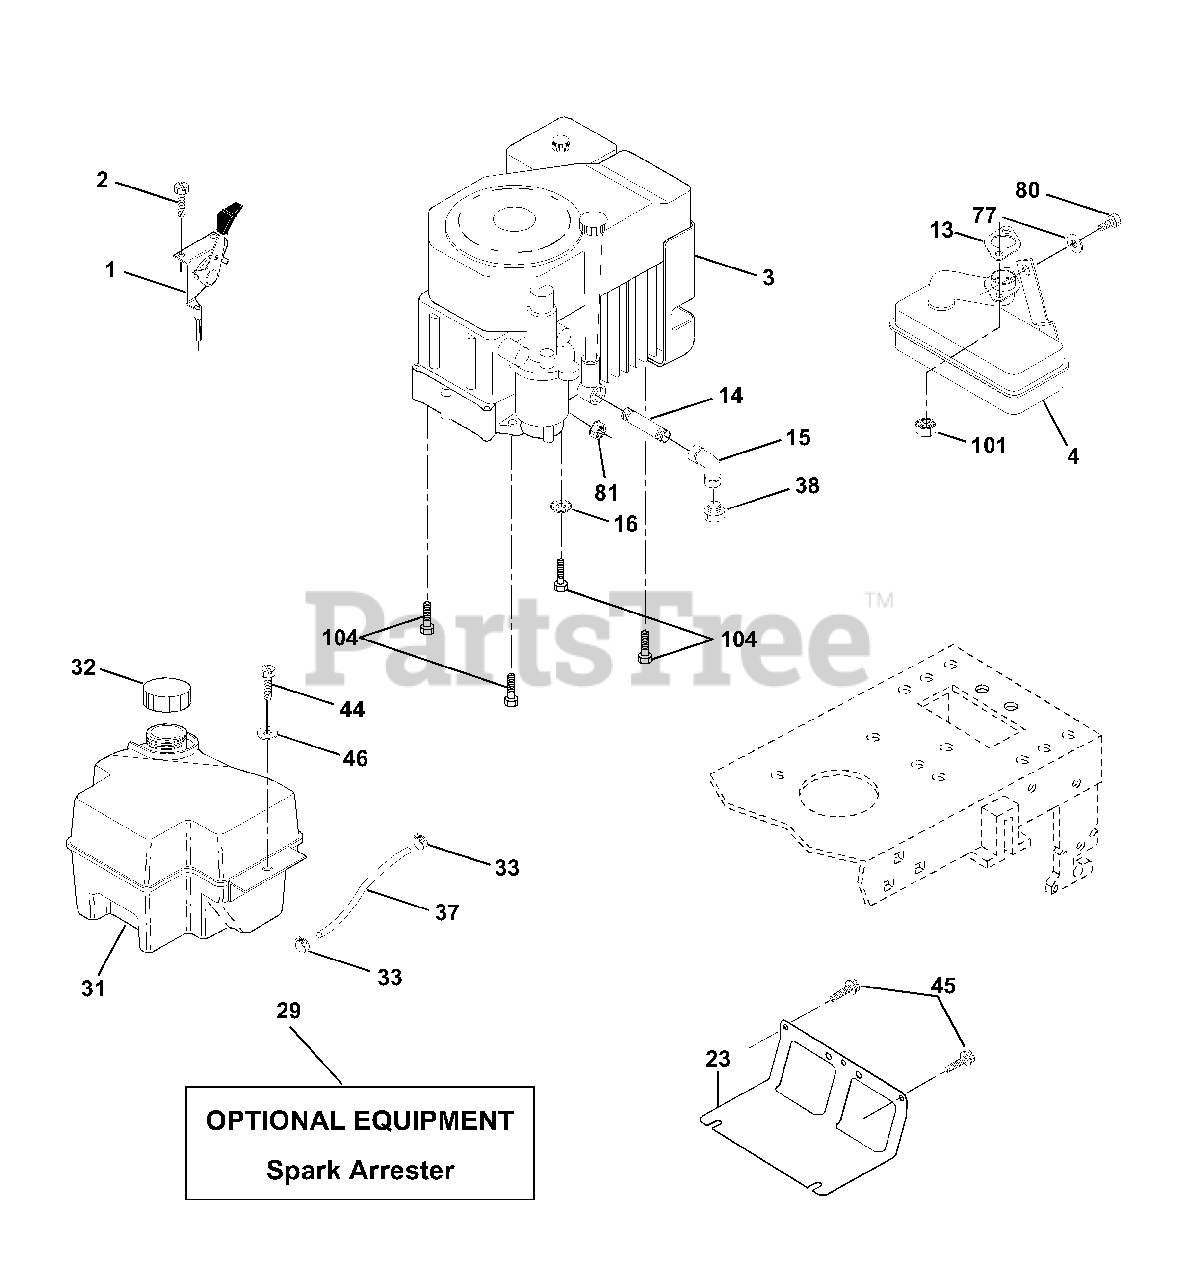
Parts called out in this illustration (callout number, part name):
1	Control, Throttle / Choke
2	Screw Hex Thd Cut 1/4-20 x 5/8
4	Muffler, Exhaust
13	Muffler Gasket
14	Nipple, Pipe
15	Elbow, Standard 90°, 3/8-18 NPT
16	Washer, Lock Ext tooth 3/8
23	Shield, Browning/Debris Guard
29	Arrester, Spark
31	Tank, Fuel
32	Cap Gauge, Fuel
33	Clamp, Hose Blk
37	Line, Fuel
38	Plug, Oil Drain
44	Screw Hexwsh Thdrol 1/4-20 x 3/4
45	Screw 3/8-16 x 3/4
46	Washer 9/32 x 7/8 x 16 Ga
77	Washer 5/16 x 3/4 x 16 Ga.
80	Bolt Hex Hd 5/16-18 Unc x 1/2
81	Nut Flange 1/4-20 Starter Nut
101	Nut Flange M8- 1.25
104	Screw 3/8-16 x 1"
